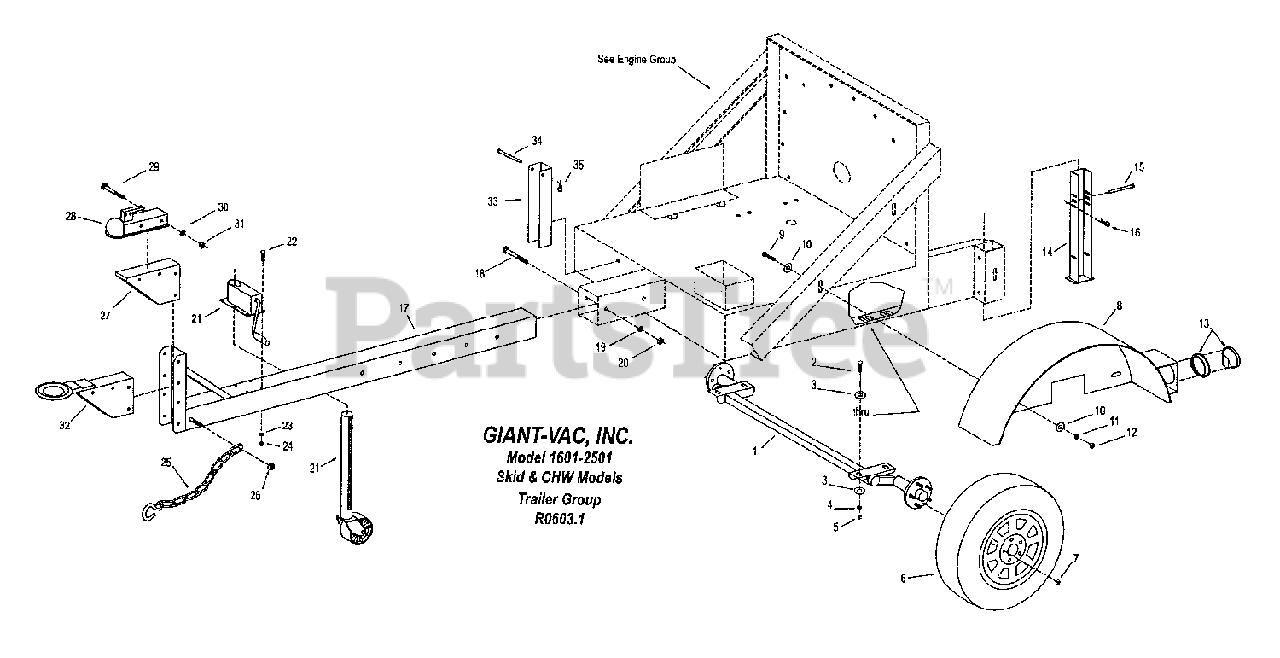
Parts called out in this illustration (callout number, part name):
1	Torflex Axle
2	1/2-13 x 1-1/4" gr 5 black oxide hex bolt
3	1/2 Flat washer
4	1/2 Lockwasher
5	1/2-13 hex end locknut
6	F78 x 15 tire and wheel assy
7	1/2-20 Lug nut
8	Fender -Left side
9	3/8-16 x 1" Hex bolt
10	3/8 Flat washer
11	3/8 Lock washer
12	3/8-16 Hex nut
13	Tail lamp (w/rubber mounting ring)
14	Support leg
15	3/8x4" Clevis pin
16	Bridge Pin
18	5/8"x4.50" Hex Bolt
19	Washer, Split Lock, ZP 5/16 Lock washer
20	5/8" Lock Nut
21	Jack, Trailer Support, 1 Wheel 600# Rack & Pinion
22	3/8"x5" Hex Bolt
23	Washer, Split Lock, ZP .375 nom
24	Bridge pin
25	Chain, w/ 1 S-Hook, ZP .313x2.00x26.00
26	.5x5 Hex Bolt
27	Ball Hitch Mount, Black
28	Ball Hitch
29	1/2"x3.500 Hex Bolt
30	1/2" Lock Washer
31	1/2"Lock Nut
32	(Optional) Pintle Ring
33	Nozzle Holder
34	Pin, Clevis, ZP. .375x4.00
35	Pin, Hair Cotter, (.0920) ZP, .375-.438 Shaft x 1.875
